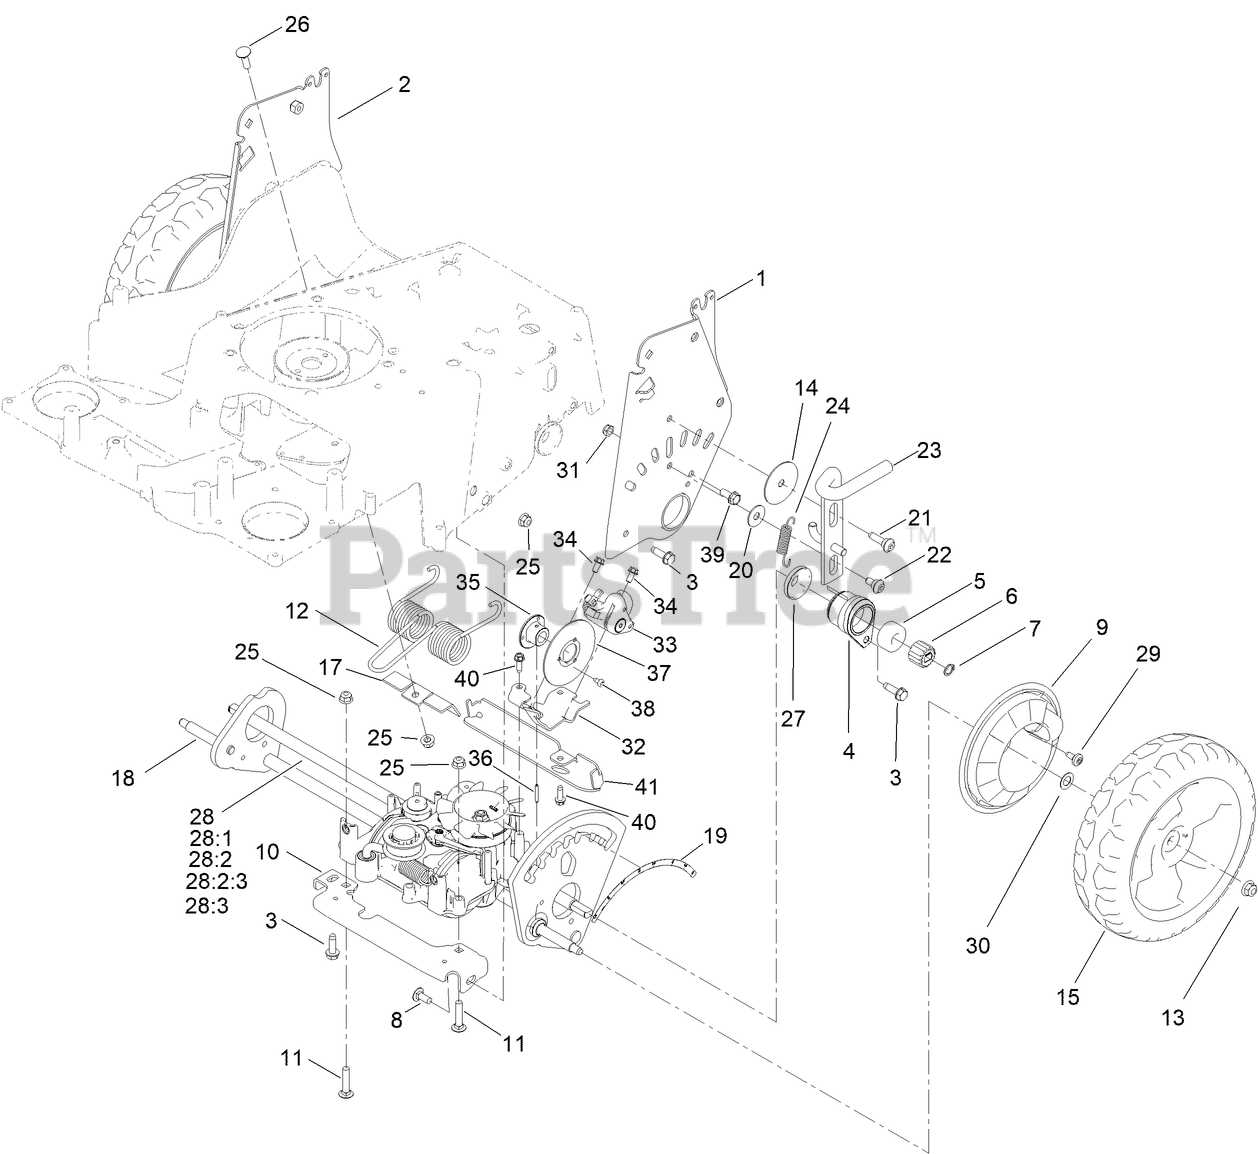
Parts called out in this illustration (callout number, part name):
1	HOC PLATE ASSEMBLY
2	HOC PLATE ASSEMBLY
3	SCREW-THD ROLL, HWH
4	BEARING RETAINER ASM
5	BEARING-BALL, CUSTOM
6	GEAR-PINION, 15T
7	RING-RETAINING
8	SCREW-CARR
9	COVER-WHEEL
10	BRACKET-TRANSMISSION, FRONT
11	BOLT-CARR
12	SPRING-TORSION
13	NUT-HF, NI
14	WASHER-PLAIN
15	10.5 IN. WHEEL ASM
17	BRACKET
18	REAR AXLE ASM
19	DECAL-HOC, REAR
20	WASHER
21	SCREW-SHOULDER, BHTF
22	BOLT-SHOULDER
23	LOCK-HEIGHT, ADJ
24	SPRING-EXTENSION
25	NUT-HF, NI
26	BOLT-CARR
27	COVER-BEARING
28	TRANSMISSION-MV702
28:1	PULLEY FAN REPAIR KIT
28:2	IDLER PULLEY REPAIR KIT
28:2:3	SPRING-TENSION, BELT
28:3	CLUTCH LEVER REPAIR KIT
29	SCREW-SHOULDER
30	WASHER-PLAIN
31	NUT-LOCK, NI
32	BRACKET-MOUNT, BRAKE
33	CALIPER-BRAKE, DISC
34	SCREW-HWH
35	HUB-ROTOR
36	PIN-ROLL
37	DISC-ROTOR
38	SCREW-TORX PH THD ROLL
39	SCREW
40	SCREW-HWHTF
41	BRACKET-SUPPORT, CABLE
